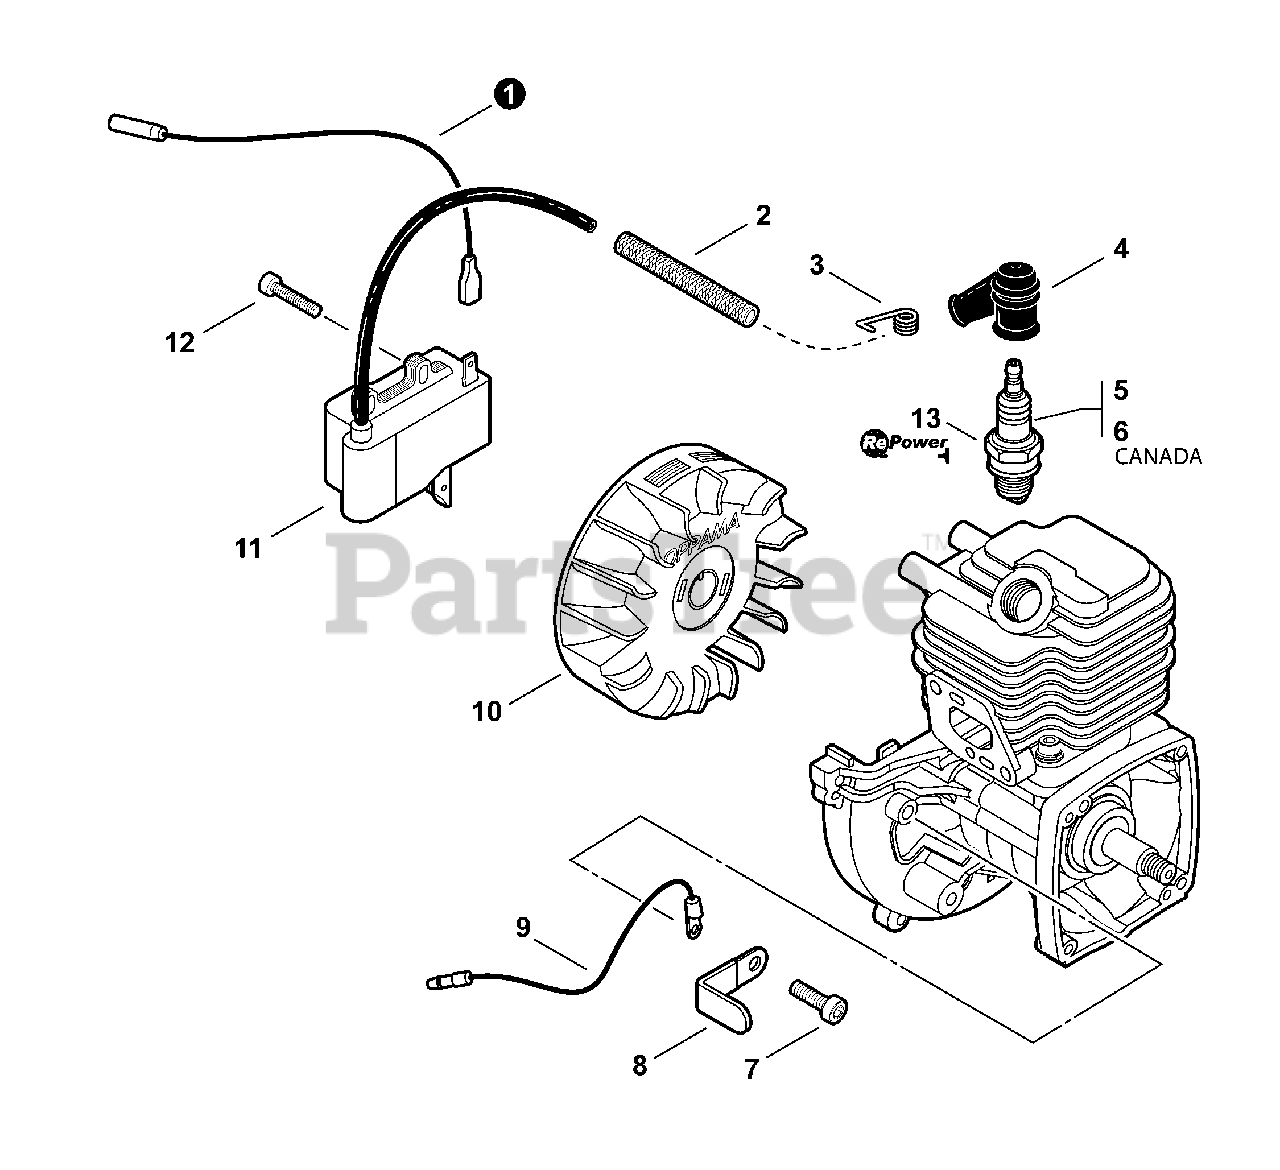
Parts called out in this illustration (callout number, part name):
1	LEAD - IGNITION L= 210
2	TUBE, INSULATOR Ø8 L= 65
3	TERMINAL, SPARK PLUG
4	CAP, SPARK PLUG
5	SPARK PLUG - BPM8Y
6	SPARK PLUG - BPMR8Y
7	BOLT, TORX 5×10
9	LEAD - GROUND
10	FLYWHEEL
11	COIL, IGNITION
12	BOLT, TORX 4×20
13	TUNE-UP KIT - REPOWER
